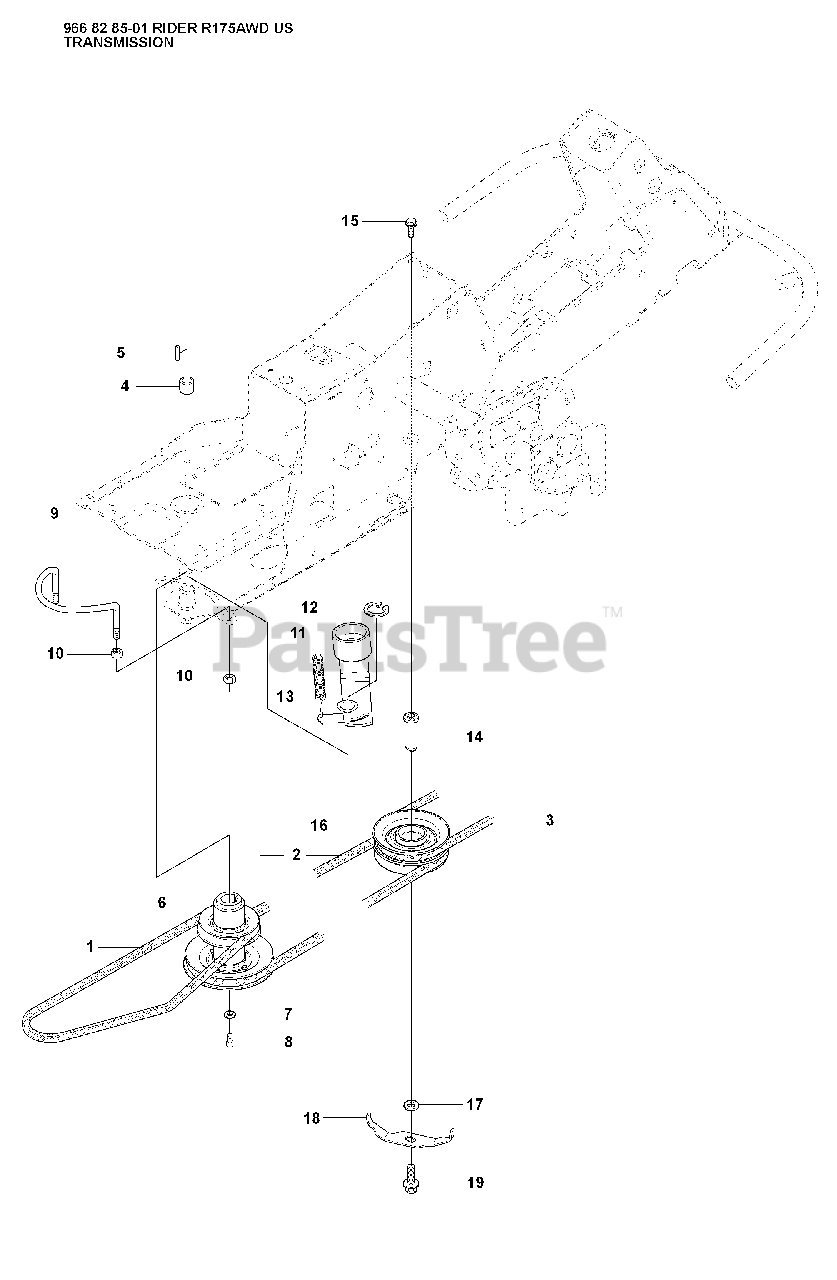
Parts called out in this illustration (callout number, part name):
1	BELT
2	BELT
3	BELT
9	Belt Guide
10	NUT
12	RETAINING RING SGA 25
14	SHAFT
18	BELT GUIDE
19	BOLT
